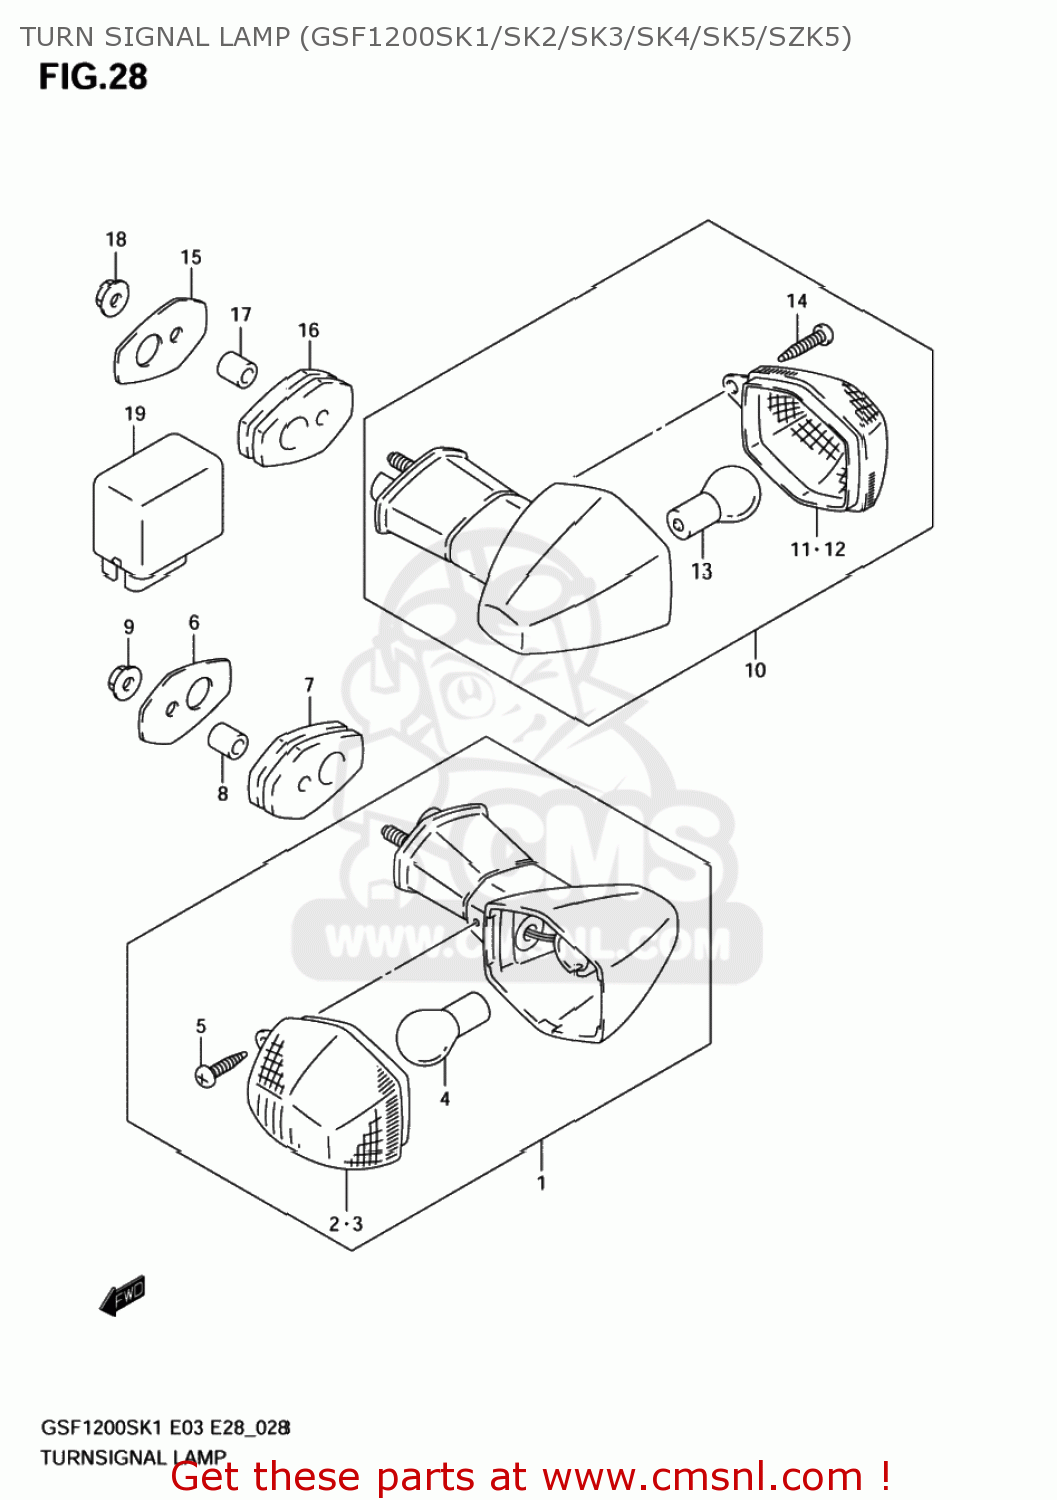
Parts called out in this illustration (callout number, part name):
1	LAMP ASSY,FR TURN SIGNAL,R
2	LENS
3	LENS
4	BULB(12V21W)
5	SCREW
6	PLATE,FR TURNSIGNAL
7	CUSHION,FR TURNSIGNAL
8	SPACER(5.5X9.5X10)
9	NUT
10	LAMP ASSY,RR TURNSIGNAL,R
11	LENS
12	LENS
13	BULB(12V21W)
14	SCREW
15	PLATE,FR TURNSIGNAL
16	CUSHION,FR TURNSIGNAL
17	SPACER(5.5X9.5X10)
18	NUT
19	RELAY ASSY,TURNSIGNAL LAMP
